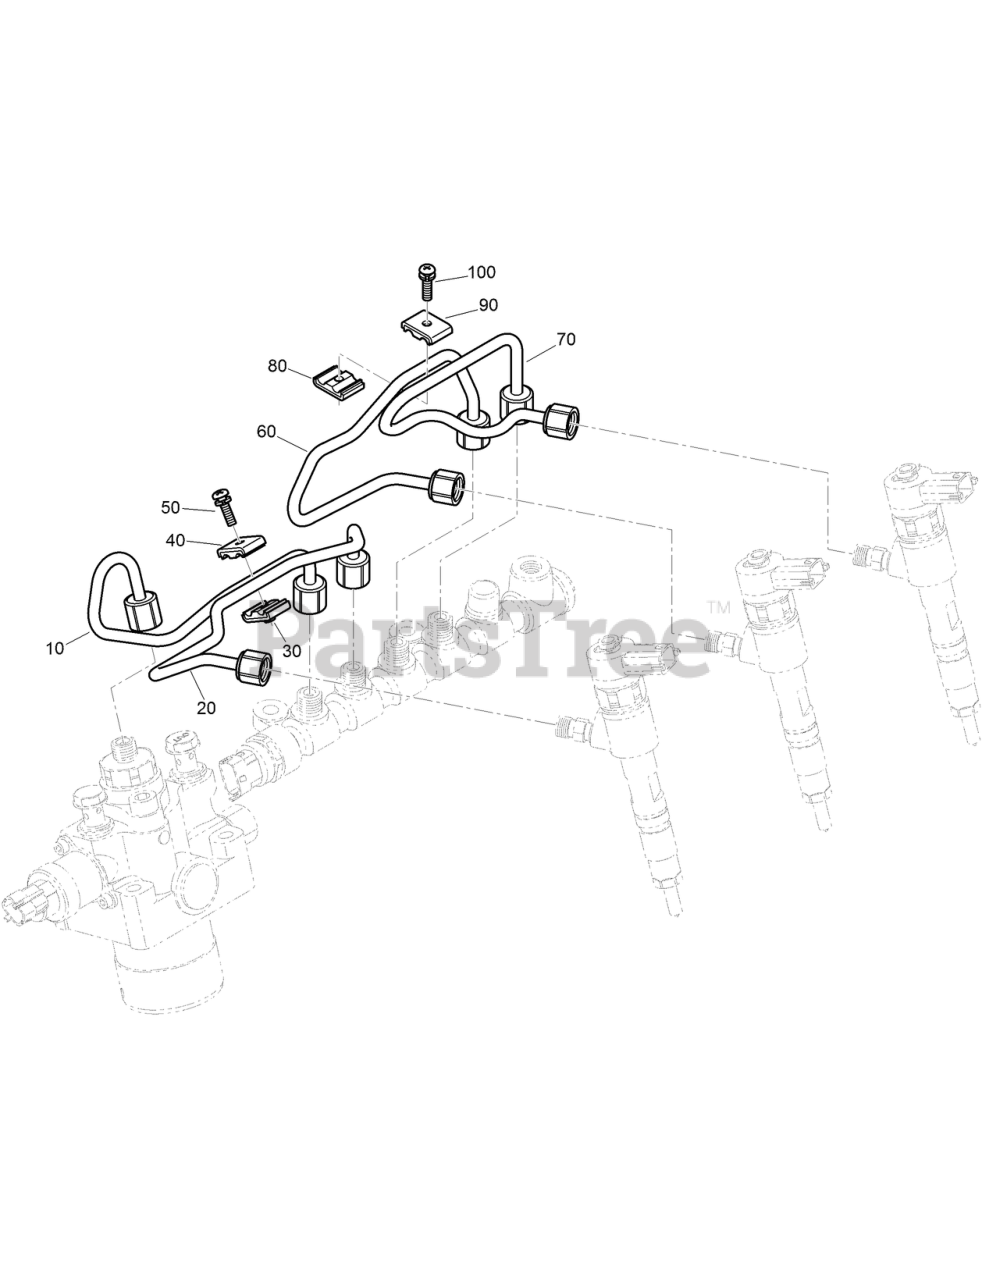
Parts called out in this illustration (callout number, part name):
20	PIPE-INJECTION
30	CLAMP-PIPE
40	CLAMP-PIPE
50	SCREW (W/WASHER)
60	PIPE-INJECTION
70	PIPE-INJECTION
80	CLAMP-PIPE
90	CLAMP-PIPE
100	SCREW (W/WASHER)
